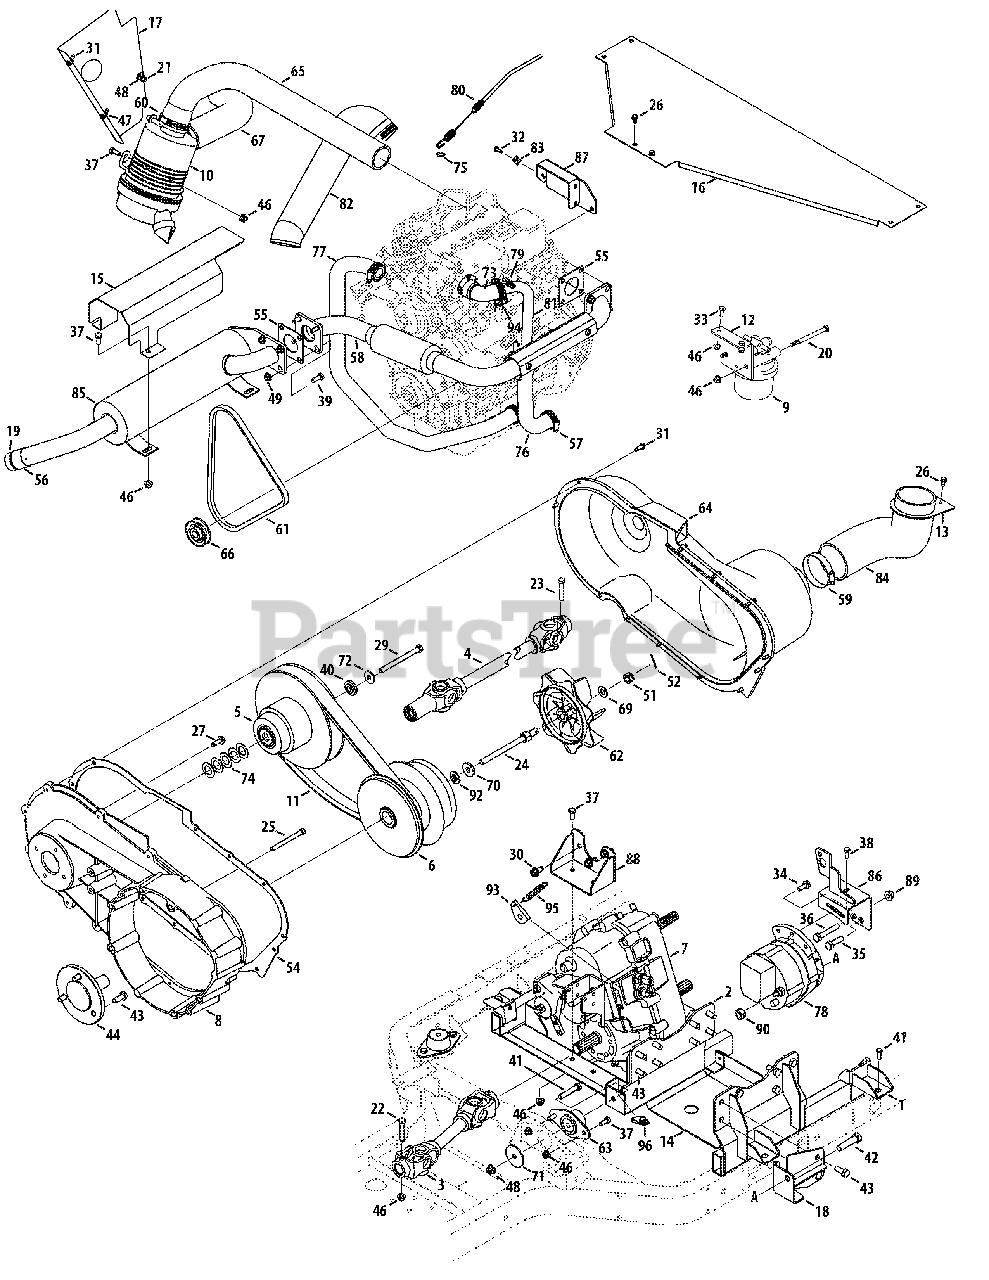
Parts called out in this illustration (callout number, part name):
1	Tray Asm, Eng, Yanmar
2	Tray Asm, Eng, Trans
3	Shifter Asm, Rr/prop
4	Shifter Asm, Frt/prop, Hilliard
5	Clutch Asm, Cvt, Driven
6	Clutch Asm, Driver, Yanmar
7	Case Asm, Transfer
8	Hsg Asm, Cvt, Yanmar; mach
9	Filter Assembly, Fuel Diesel
10	Filter Assembly, Aircl, Yanmar
10	Filter, Air
10	Valve, Dust
11	Belt, Cvt, 4x4
12	Brkt, Fltr, Fuel Yanmar
13	Brkt, Tube, CVT
14	Shld, Oil, Eng
15	Exh, Shield, Heat
16	Plt, Heat, Shield, Yanmar
17	Plt, Baffle
18	Bracket. Mt, Lwr, Alternator
20	Hhcs, 5/16-18, 4.00, Gr5, Std
21	Hhcs, 3/8-16, .75, Gr5, Std
22	Hhcs, 5/16-18, 2.00, Gr5, Patch
23	Hhcs, 5/16-18, 1.875, Gr5, Patch
24	Hhcs, 7/16-20, 5.00, Gr5, Special
25	Scr, M10-1.50
26	Scr, Tt, 1/4-20, 0.500, Hxindwsh
27	Scr, Tt, 5/16-18, 1.000, Hxindwsh
28	Scr, B, 5/16-12, 0.500, Hxindwsh
29	Hhcs, 3/8-24, 4.50, Gr5, Std
30	Scr, Tt, 3/8-16, 0.750, Hxindwsh
31	Scr, Tt, 1/4-20, 0.750, Hxindwsh
32	Scr, #10-16, 0.625, Hxindwsh
33	Scr, Ab, 5/16-12, 0.750, Hxindwsh
34	Hhcs, 5/16-18, .875, Gr5, Std
35	Hhcs, M8-1.5, 35 mm, Gr8.8, Std
36	Hhcs, M10-1.5
37	Hhcs, 5/16-18, .75, Gr5, Std
38	Hhcs, 1/4-20, .75, Gr5, Std
39	Hhcs, 5/16-18, .875, Gr5, Std
40	Spcr., Shldr.
41	Hhcs, 3/8-16, 2.00, Gr5, Std
42	Hhcs, 1/2-13, 2.00, Gr5, Std
43	Hhcs, M10-1.5, 25mm, Gr5
44	Shf, Output, Yanmar, Tapered
45	Nut, hxlk, #10-24
46	Nut, Flglk, 5/16-18, Grf, Nylon
47	Nut, Flglk, 1/4-20, Grf, Nylon
48	Nut, Flglk, 3/8-16, Grf, Nylon
49	Nut, Flglk, 5/16-18, Gr5, Sd Lk
50	Nut, Hexlk, 5/16-18, Grb, Ctrlk
51	Nut, Hex, 1/2-20, Gr5, Slot
52	Pin, Cot, 3/32, 1.0
53	Pin, Spirol, 5/16 x 1.75
54	Gskt, CVT Cover
55	Gskt, Eng
56	Arstr, Scrn, Spark
57	Clamp, Hose, Adj
58	Pipe, Exh, Yanmar
59	Clamp, Hose, Adj
60	Clamp, Hose, Adj 2-3"
62	Impeller, Blo
63	Mt, Comprs, Eng, Hd
65	Hose, Air Inlet, Yanmar
67	Hose, Air Inlet
68	Wash, Flat, .330 X .630 X .0635
69	Wash, Flat, .510 X 1.00 X .060
70	Wash, Flat, .450x1.250x.164, Ht
71	Wash, Flat, .38 X 2.00 X .12
72	Wash, Bell, .396 X 1.140 X .095
73	Tube, Upr, rr, Rdtr, Yanmar
74	Wash, Fl, .793x1.368 X.025, Ht
75	Wash, Lock, 5/16 Ext Tooth
76	Tube, lwr, rdtr
77	Hose, Rdtr, Rr, Yanmar
78	Altnr, Aux, 65 Amp
79	Ftg, Petcock, 1/8"
80	Cable, Cont, Throttle, Yanmar
81	Tube, Rdtr
82	Hose, CVT, Exhaust
83	Clamp, Casing
84	Tube, Cvt, Intake
86	Mount Assembly, Alternator, Yanmar
87	Bracket, Mt, Throttle
88	Bracket, Mt, Trans, rr
89	Nut, Hex, Flg, Lk
90	Nut, Hxlk, 1/2-13
91	Nut, Flg, M8-1.25
92	Spcr., Shldr.
93	Bracket, throttle, spring, return
95	Spring, Extension
